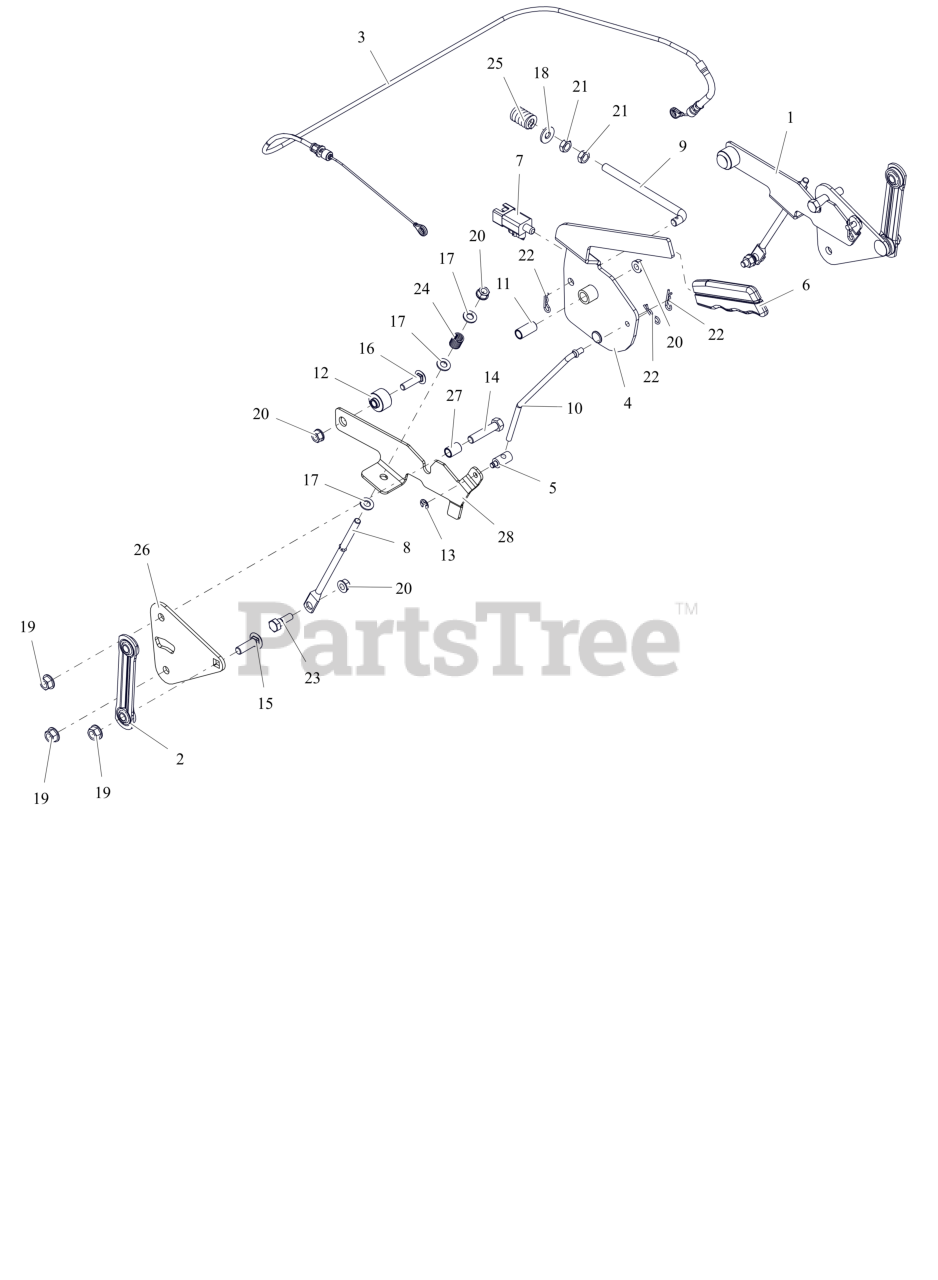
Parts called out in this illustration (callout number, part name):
1	ARM, BRAKE - LH (W/PIN)
2	LINK, STAMPED STEERING
3	CABLE, BRAKE - PARKING
4	HANDLE, PARKING BRAKE - WLDMT (BLACK)
5	TRUNION, 1/4-20
6	GRIP, PARKING BRAKE (GREY)
7	SWITCH, SNAP IN - N.O./N.O.
8	ROD, LINK - TRANSMISSION BRAKE
9	ROD, OVER CENTER
10	ROD, BRAKE LINK
11	BSHG-SLV .385X.500X1.045
12	SPCR, FLANGE
13	RG-RTNG-EXT .250X.025
14	BLT, HEX .38-16X1.75 G5 ZCC
15	BLT,RHSSN .38-16X1.25 G5 ZCC
16	BLT, RHSSN.31-18X1.25 G5 ZCC
17	WSHR,FLT .344X.688X.065 ZCC
18	WSHR,FLT .375X.875X.083 ZCC
19	NUT-LK-TOP-FLG .38-16 ZC120
20	NUT-LK-TOP-FLG .312-18 GF ZCC
21	NUT-JAM .375-16 G2 ZCC
22	PIN, HAIR #213 .08X1.19 ZCC
23	BOLT,SHLDR .38X.25 -.31-18X.75
24	SPRING, COMPRESSION
25	SG-COMP .187X.56X1.62
26	PLATE, TRANSAXLE (BLACK)
27	SPCR SLEEVED .385X.500X.718
28	ARM, BRAKE - RH
